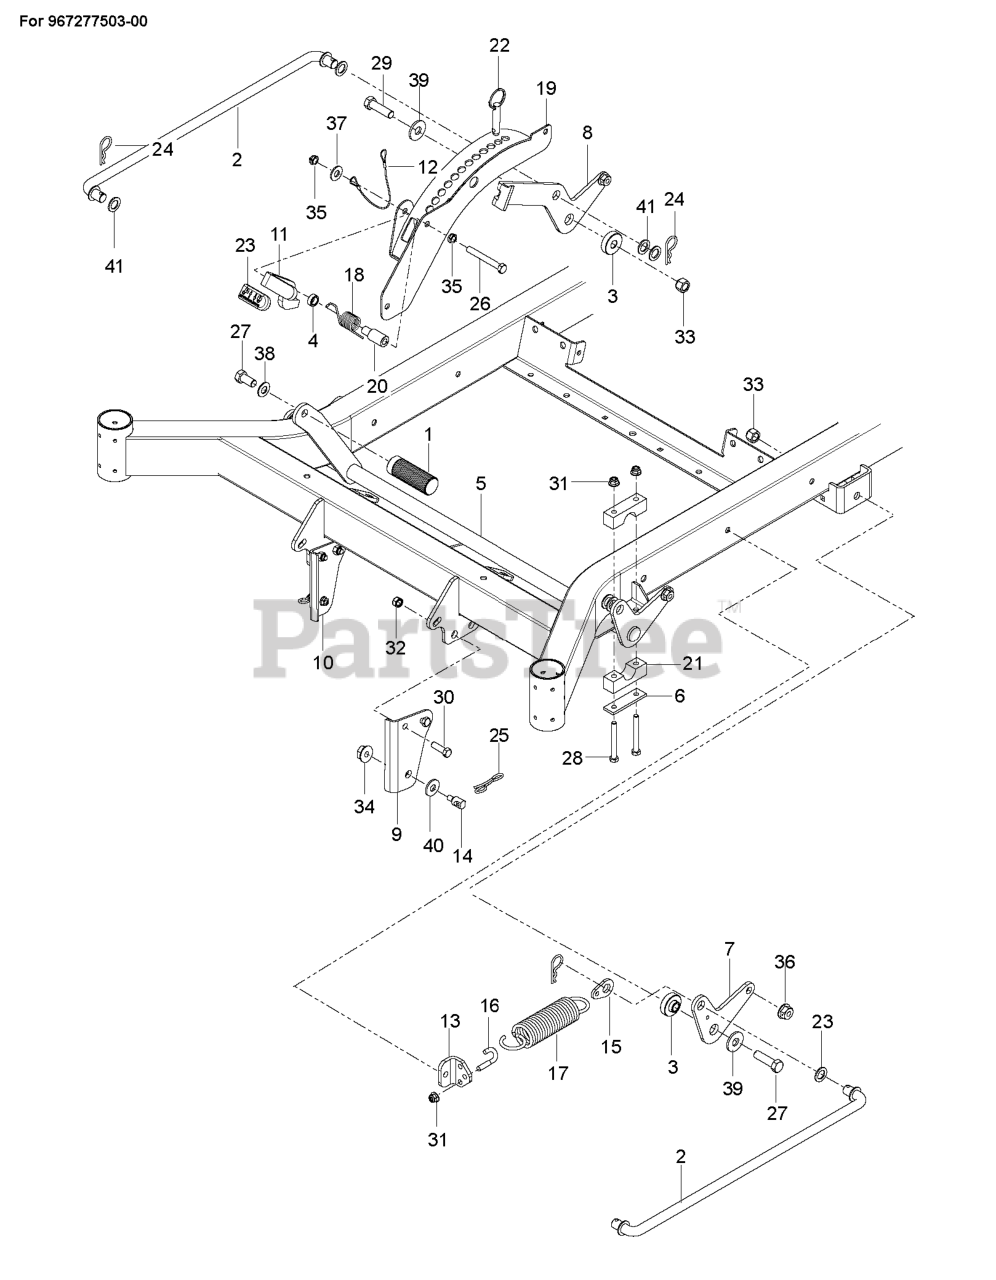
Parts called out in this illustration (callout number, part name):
1	PEDAL, DECK HEIGHT
2	CROSS LINK
3	SPACER.IDLER.METAL.POWDER
4	SPACER, .3
5	LIFT.PNT.MZ.DECK.WELD.E-DIP
6	REINFORCEMENT.PLATEX431
7	BELLCRANK, RR, LIFT
8	BELLCRANK, RR, RT
9	BRACKET.PNT.SUSP.CHAS.FR.LH.OR
10	BRACKET.PNT.SUSP.CHAS.FR.RH.OR
11	LATCH, TRANSPORT
13	MOUNT, SPRING
14	STUD.FASTNER.W/ANTI-ROTATE
15	TAB, SPRING
18	SPRING, TORSION
19	HEIGHT, ADJUST, DECK
20	PIVOT, LATCH, TRANSPORT
21	PILLOW BLOCK
22	PIN, 1/2 X 1 1/2, DETENT RING
23	GRIP, TRANSPORT-RELEASE
24	PIN, COTTER 1 3/4
25	PIN.COTTER.7/16.BOW TI.
26	BOLT.HEX.FIN.3/8-16 X 3.GR5
27	HHCS 1/2-13 X 1
29	HCS 1/2-13 X 1 3/4 GR 8
30	HCS 3/8-16X1.GRD.5.ZD
31	5/16-18 NYLOC FLANGE NUT
32	NUT 3/8-16 NYLOC
33	NUT.LK.W/WSH.1/2.
34	NUT LOCK HEX FLANGE 5/16-18
35	NUT HEX 3/8-16 NYLON, THIN
36	NUT LOCK FLG 3/8-16 UNC
37	RP WASHER 3/8 FLAT
38	CONTACT BELLSPR 1/2
39	WASH USS FLAT 1/2
40	WASHER.CLEAR.ZINC
